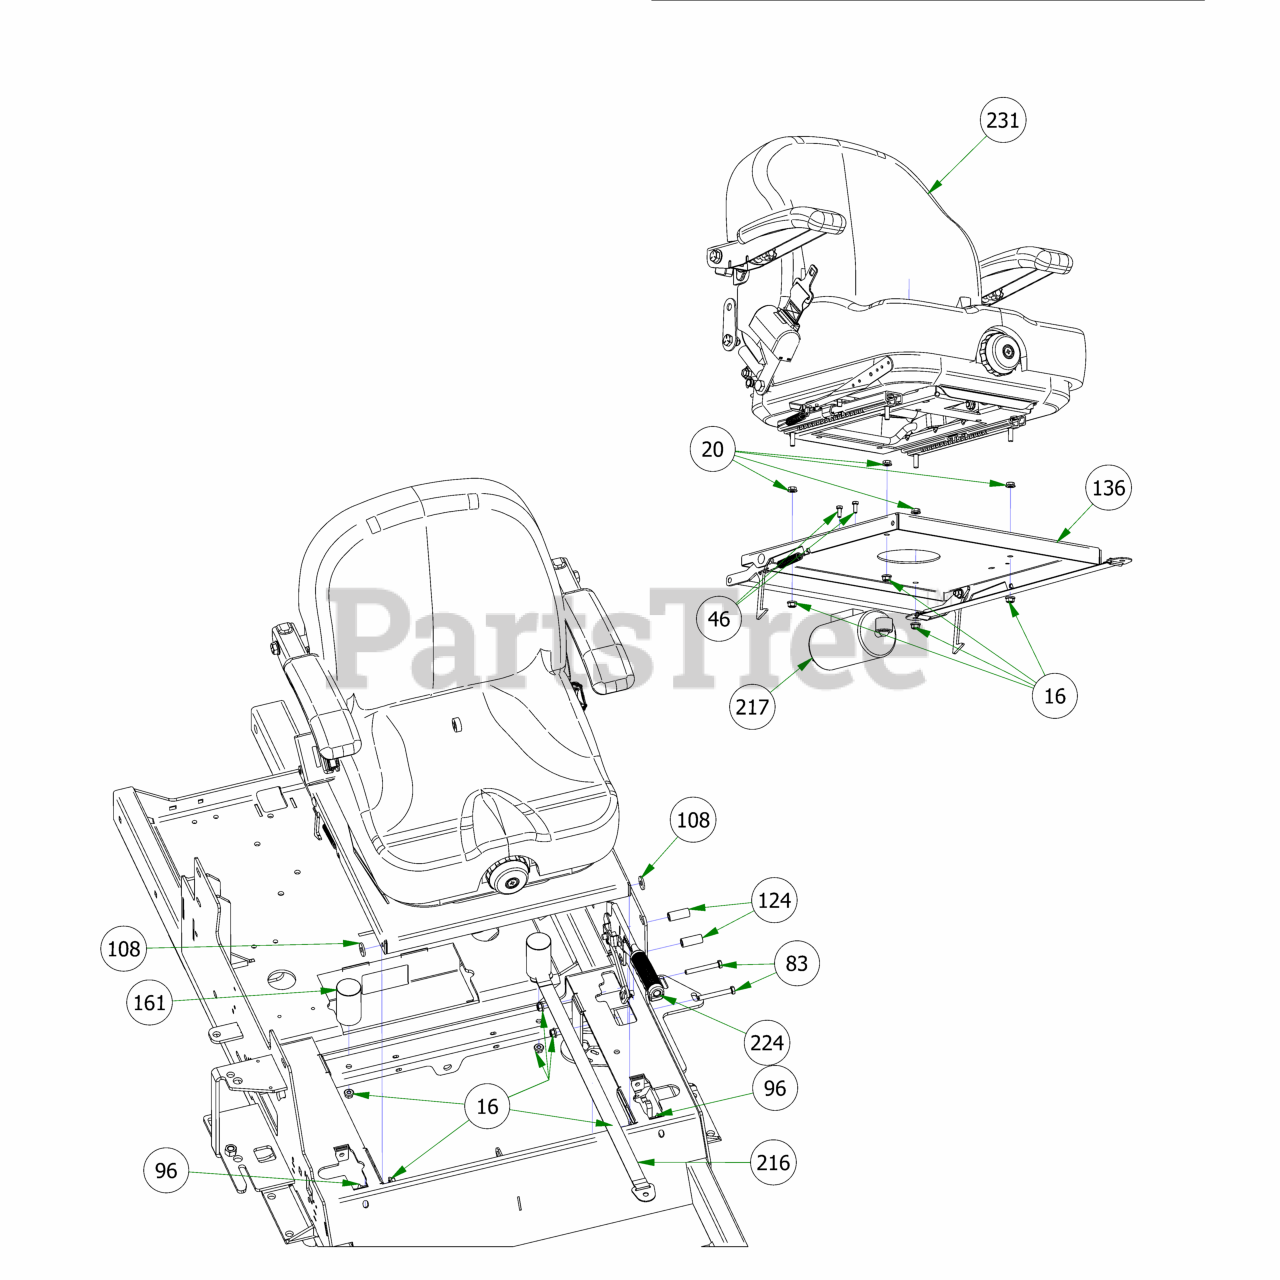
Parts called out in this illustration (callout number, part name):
16	5/16-18 NYLON INSERT FLANGE LOCKNUT ZINC
20	5/16-18 HEX SERRATED FLANGE NUT HARD/ZINC
46	M6-1.0 X 16MM DIN 933 HEX TAP BOLT (CL 8.8) ZINC
83	5/16-18 X 2-1/2 HEX CAP SCREW (GR.5) ZINC
96	5/16-18 X 1 CARRIAGE BOLT (GR.8) ZINC
108	.360 ID X .983 OD X .120 THICK FLAT WASHER NYLON
124	.380 ID X .625 OD X 1.500 LGTH 2019 OUTLAW BRAKE HANDLE SPACER ZINC
136	R-SERIES SEAT PLATE ASSEMBLY
161	2019 Bad Boy X Cylindrical Seat Mount
216	Seat Strap with Buckles
217	2019 Outlaw EPA Cannister Assembly
224	2019 Brake Handle Assembly
230	2019 Renegade Gas Frame - Powdercoated
231	2022 Suspension Seat w/Seatbelt
